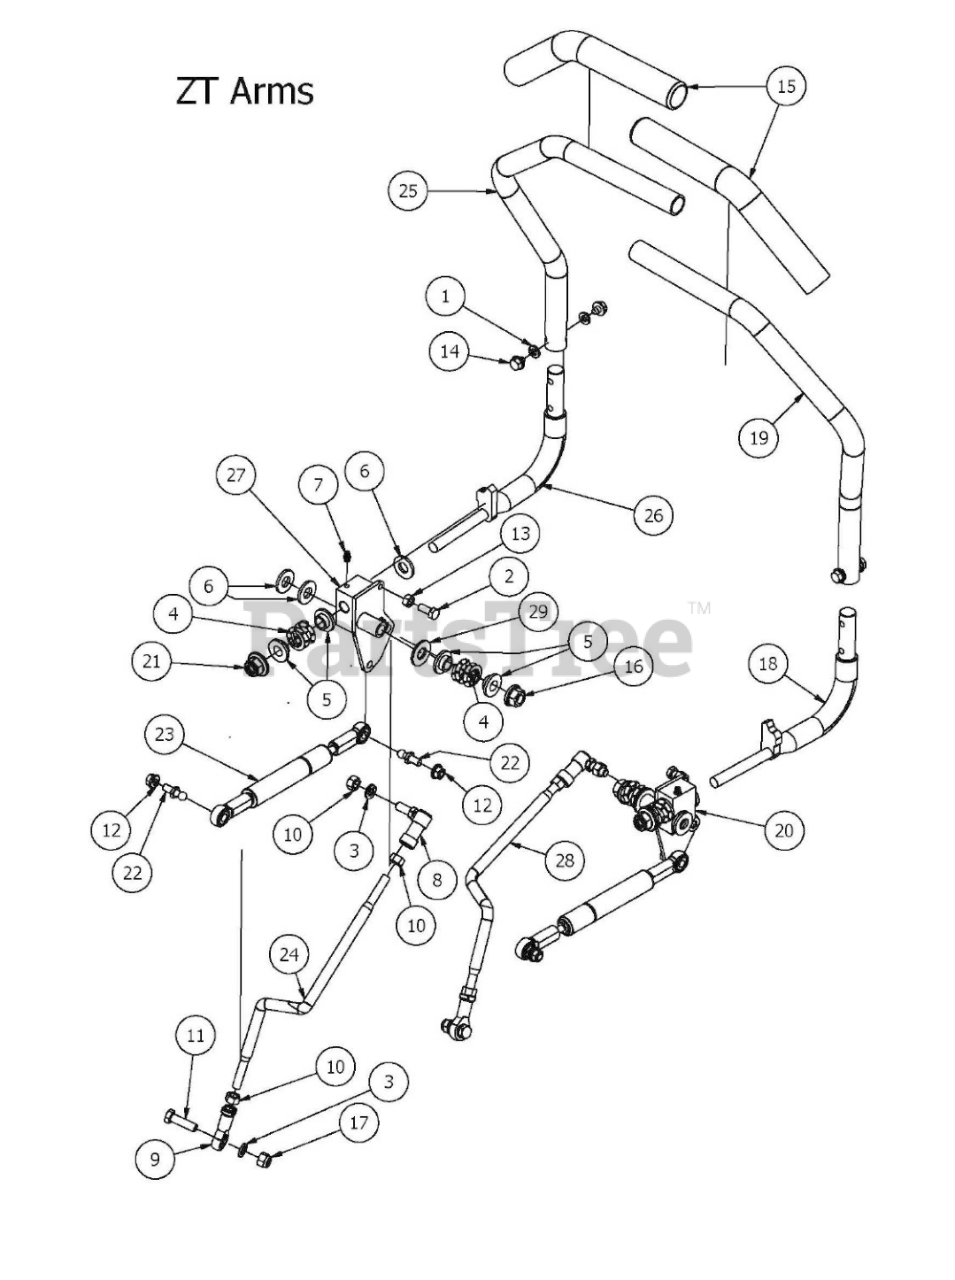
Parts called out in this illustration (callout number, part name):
1	5/16" Lock Washer
2	5/16" x 3/4" Hex Bolt
3	3/8" Lock Washer
4	Drive Lever Spring
5	.515 ID Nylon Shoulder Washer
6	.505 Nylon Spacer
7	1/4" Press in Grease Fitting
8	3/8-24 Quick Release Ball Joint
9	Spherical Rod End - Outlaw
10	3/8" Fine Threaded Jam Nut
11	3/8" x 1 1/4" Hex Bolt
12	5/16-18 Hex Flange Nut
14	5/16-18 1/2 HWH Bolt-Steering
15	Rubber Grip
16	1/2-13 Mechanical Lock Nut
17	3/8 Nylock Nut
18	Steering Arm Elbow - Right
19	ZT Direction Steering Arm (Right)
20	2017 Drive Lever Housing - Right
21	1/2-13 Nylon Insert Flange Nut
22	10mm Damper Ball Stud-Steering
23	Steering Damper
24	Push Rod Left
25	ZT Direction Steering Arm (Left)
26	Steering Arm Elbow - Left
27	2017 Drive Lever Housing Left
28	Push Rod Right
29	1/2" Washer (Grade 8)
